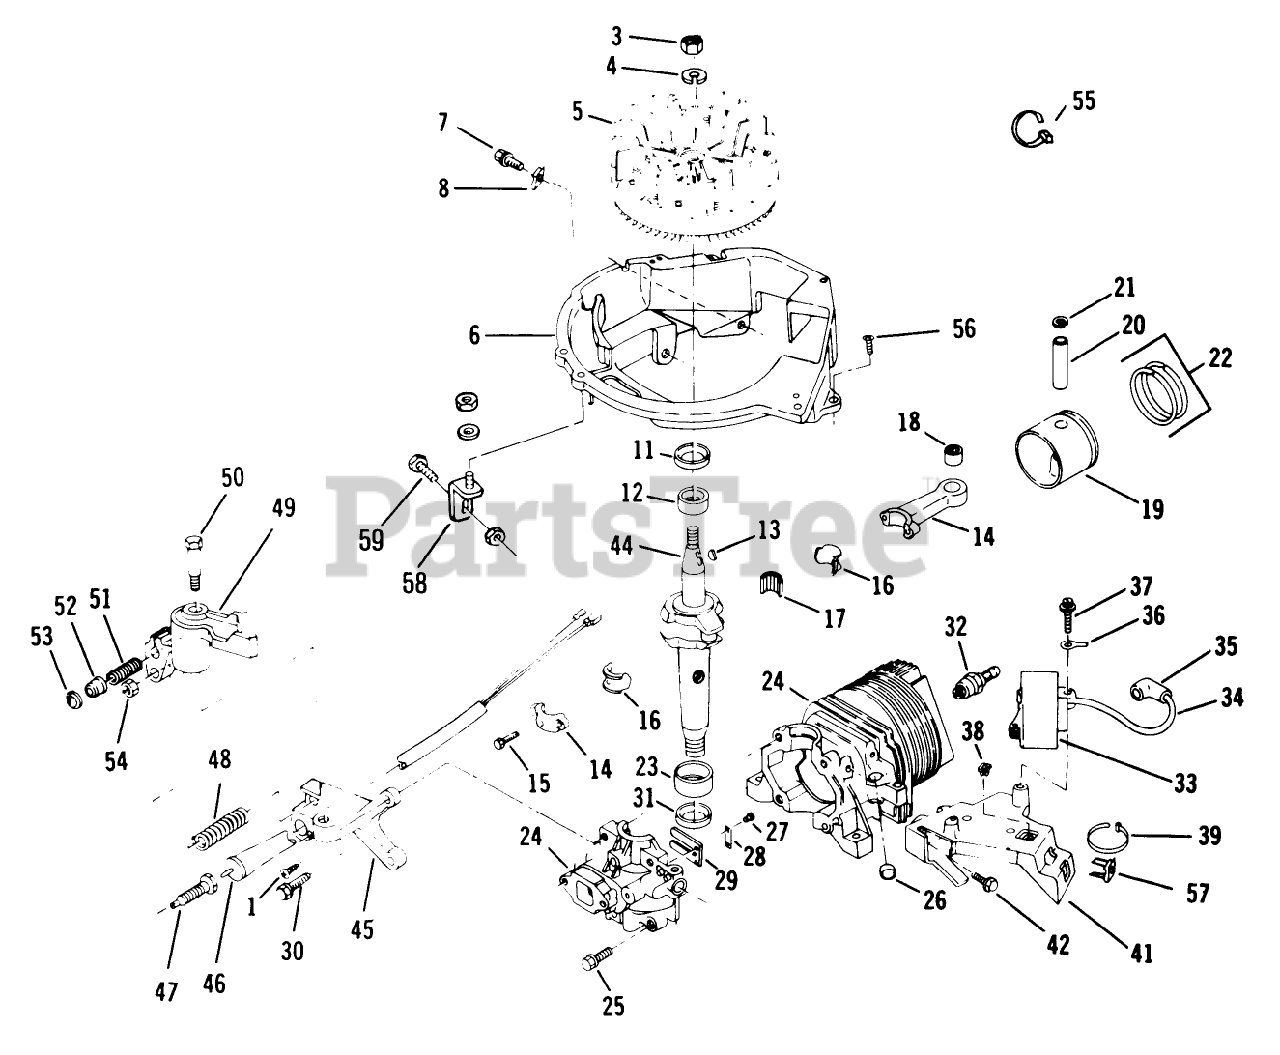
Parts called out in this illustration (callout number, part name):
1	SCREW F
3	NUT
5	FLYWHEEL ASSY F
6	BASE SHROUD F
7	SCREW-SEMS
12	BEARING V
13	KEY
15	SCREW-HSH
16	LINER ASM
18	BEARING AY F
21	RING-RETAINING
23	BEARING V
25	SCREW S
26	PLUG-CORE VF
28	PLATE-BACKUP, REED
31	SEAL-OIL
34	HT LEAD&COVER XEV
36	TERMINAL S
38	NUT-CLIP
41	BRACKET S
45	BRACKET-BRAKE F
47	PLUNGER S
48	SPRING-BRAKE
51	SPRING
52	ACTUATOR-LEVER, BRAKE
53	RETAINER S
54	Nut
56	SCREW F
57	NUT-CLIP
58	BRACE AY F
59	BOLT F
60	WASHER S
